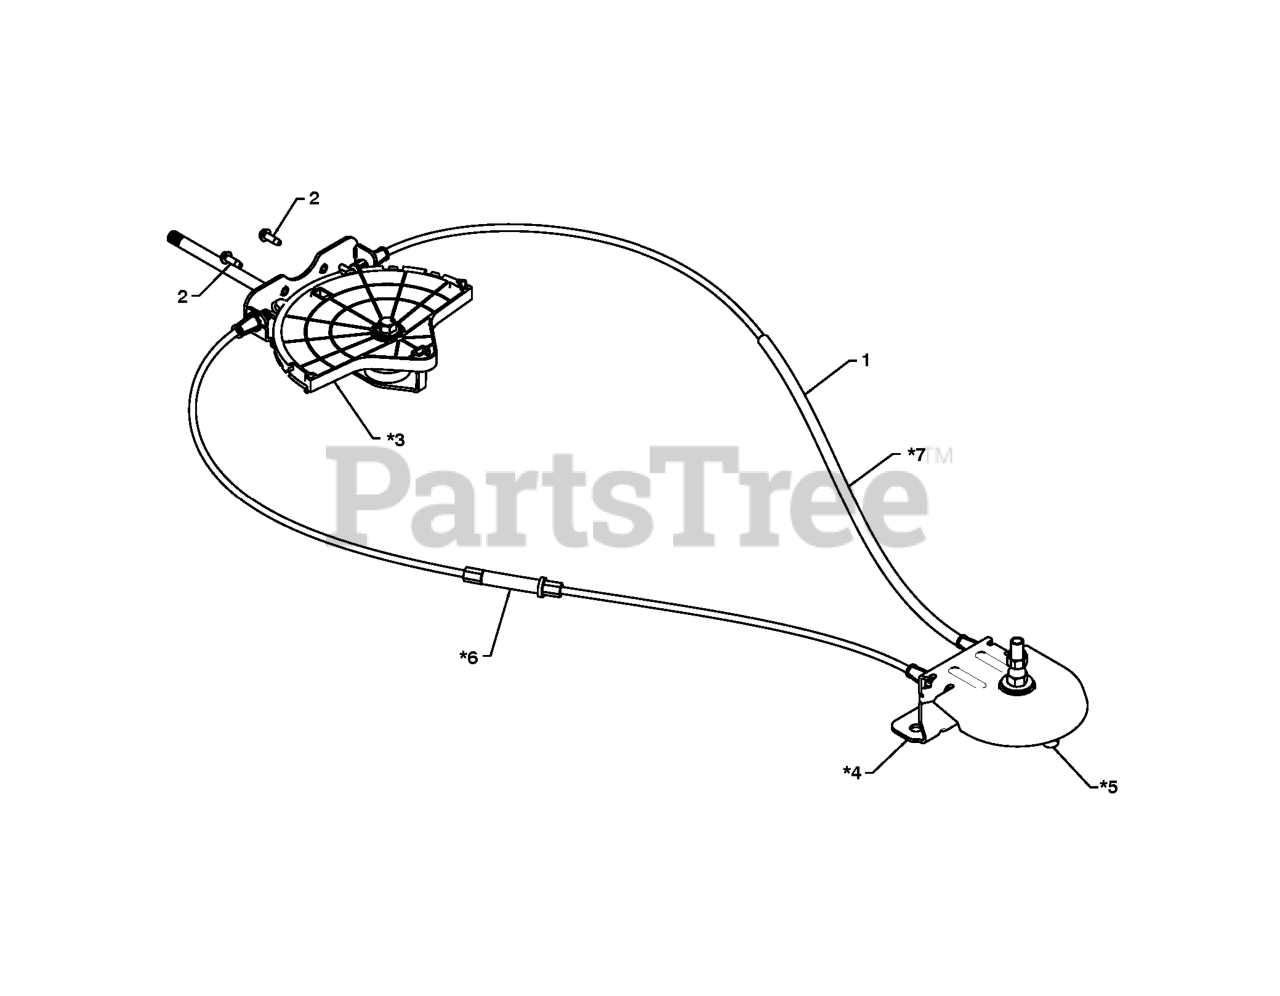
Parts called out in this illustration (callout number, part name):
1	RB LEVER.CABLE.ASM.ROTATR.PLTD
2	SCREW #10-24 X 5/8
3	CHUTE.ROT.HEAD.SERVICE
4	SNOW.PIVOT.BRKT.GRY.SERVICE
5	SNOW.PIVOT.PULLY
6	SNOW.CABLE.ASM.ADJUSTABLE.GRAY
7	SNOW.CABLE.ASM.SERVICE
